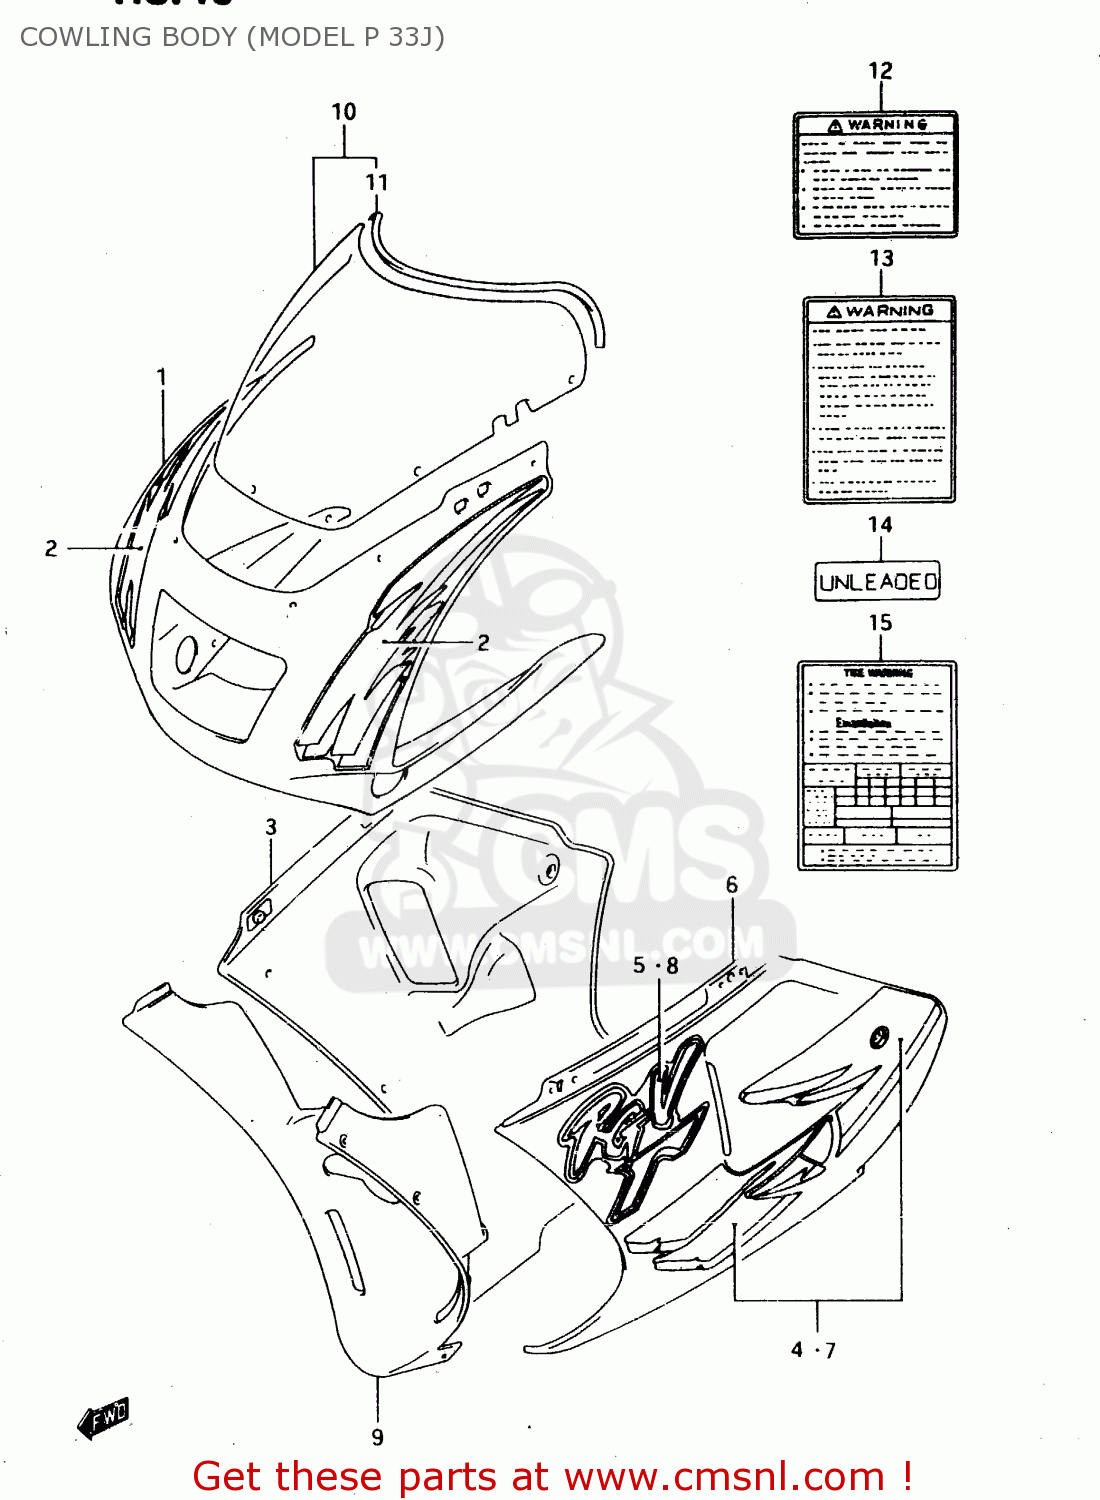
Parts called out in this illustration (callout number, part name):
1	COWLING ASSY, BODY (BLACK)
2	TAPE SET,COWL BODY
3	COWLING,UNDER
4	TAPE SET,COWL UNDER,R
5	EMBLEM,COWLING UNDER,R
6	COWLING ASSY,UNDER,L
7	TAPE SET,COWL UNDER,L
8	EMBLEM,COWLING UNDER,L
9	COWLING,UNDER CTR
10	SCREEN SET,WIND
11	MOLDING WINDSCREEN
12	LABEL
13	LABEL (WARNING SCREEN)
14	LABEL,CAUTION
15	LABEL, TIRE AIR PRESSURE
